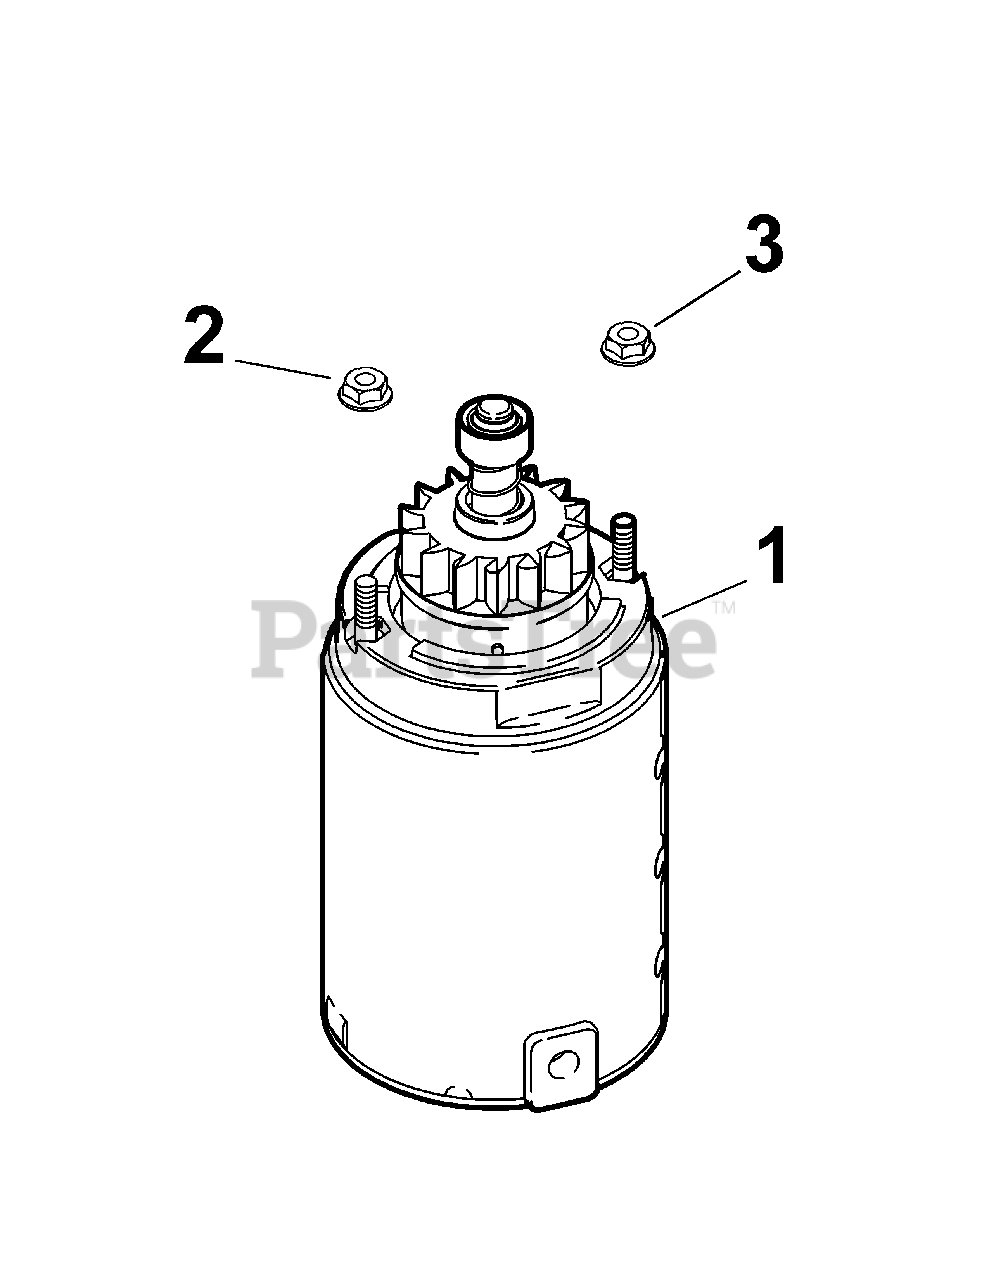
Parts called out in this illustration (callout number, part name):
1	Starter Assembly
2	Hex Nut, #10-24
3	Flange Nut, 1.4-20
